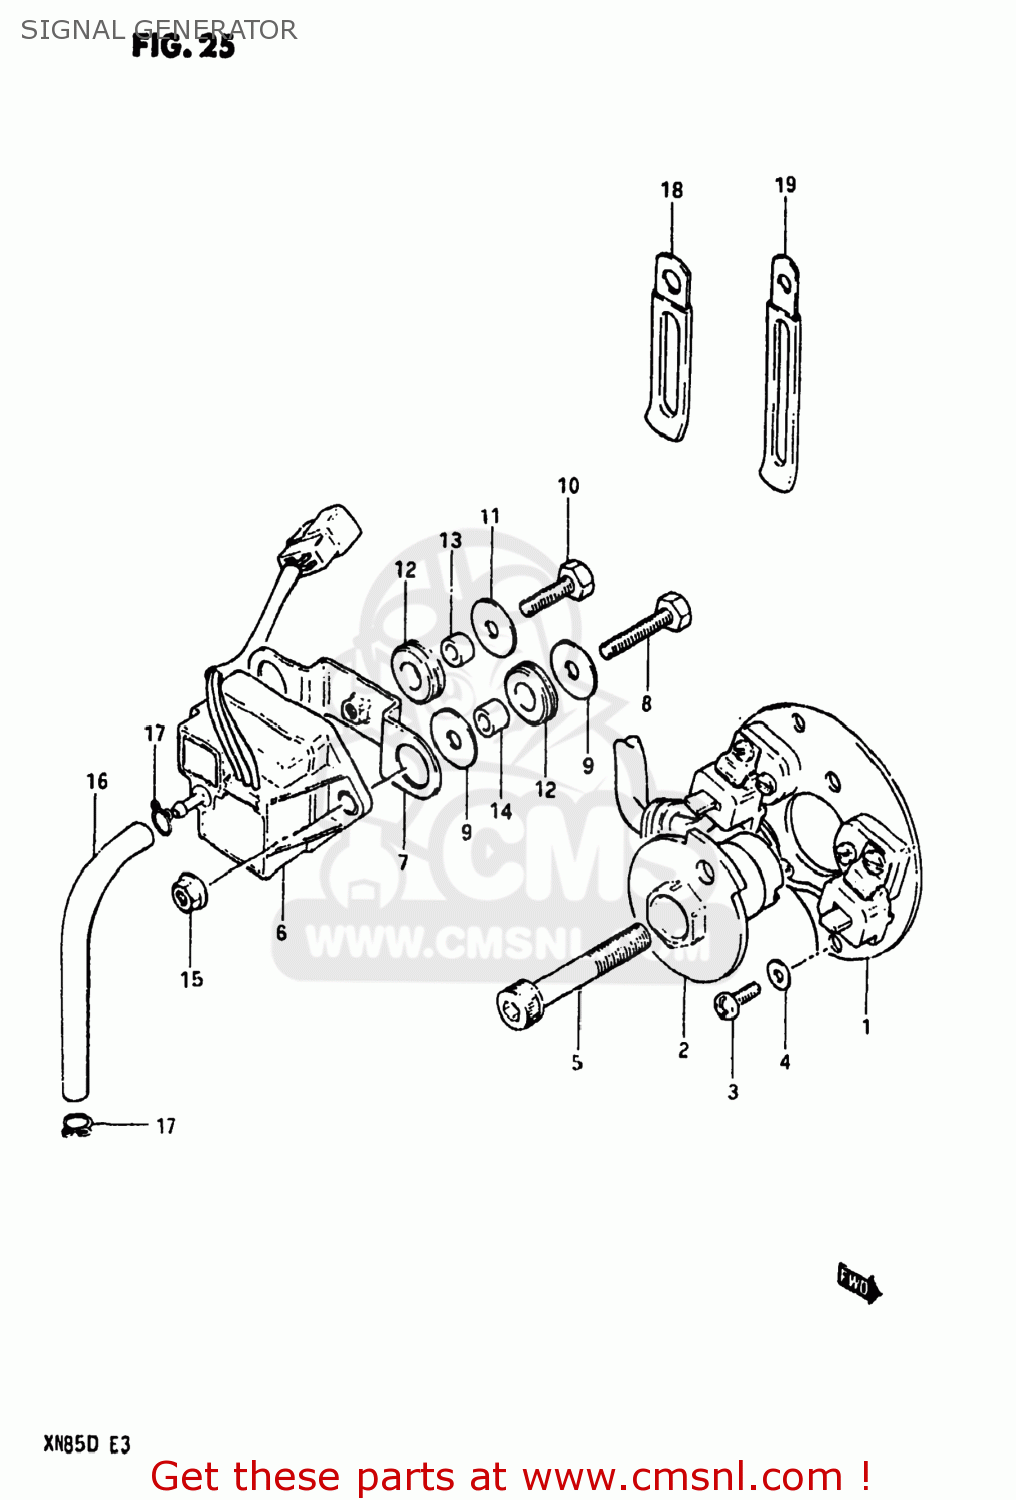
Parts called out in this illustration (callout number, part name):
1	GENERATOR ASSEMBLY,SIGNAL
2	GOVERNOR ASSEMBLY
3	SCREW(5X12)
4	WASHER(5.5X10X0.8)
5	BOLT
6	SENSOR ASSEMBLY,IGNITER
7	BRACKET,BOOST SENSOR
8	BOLT
9	WASHER
10	BOLT, UPPER
11	WASHER
12	CUSHION
13	SPACER(6.1X9X7.5)
14	SPACER (6.1X9X9)
15	NUT
16	HOSE
17	CLIP
18	CLAMP L:35
19	CLAMP
